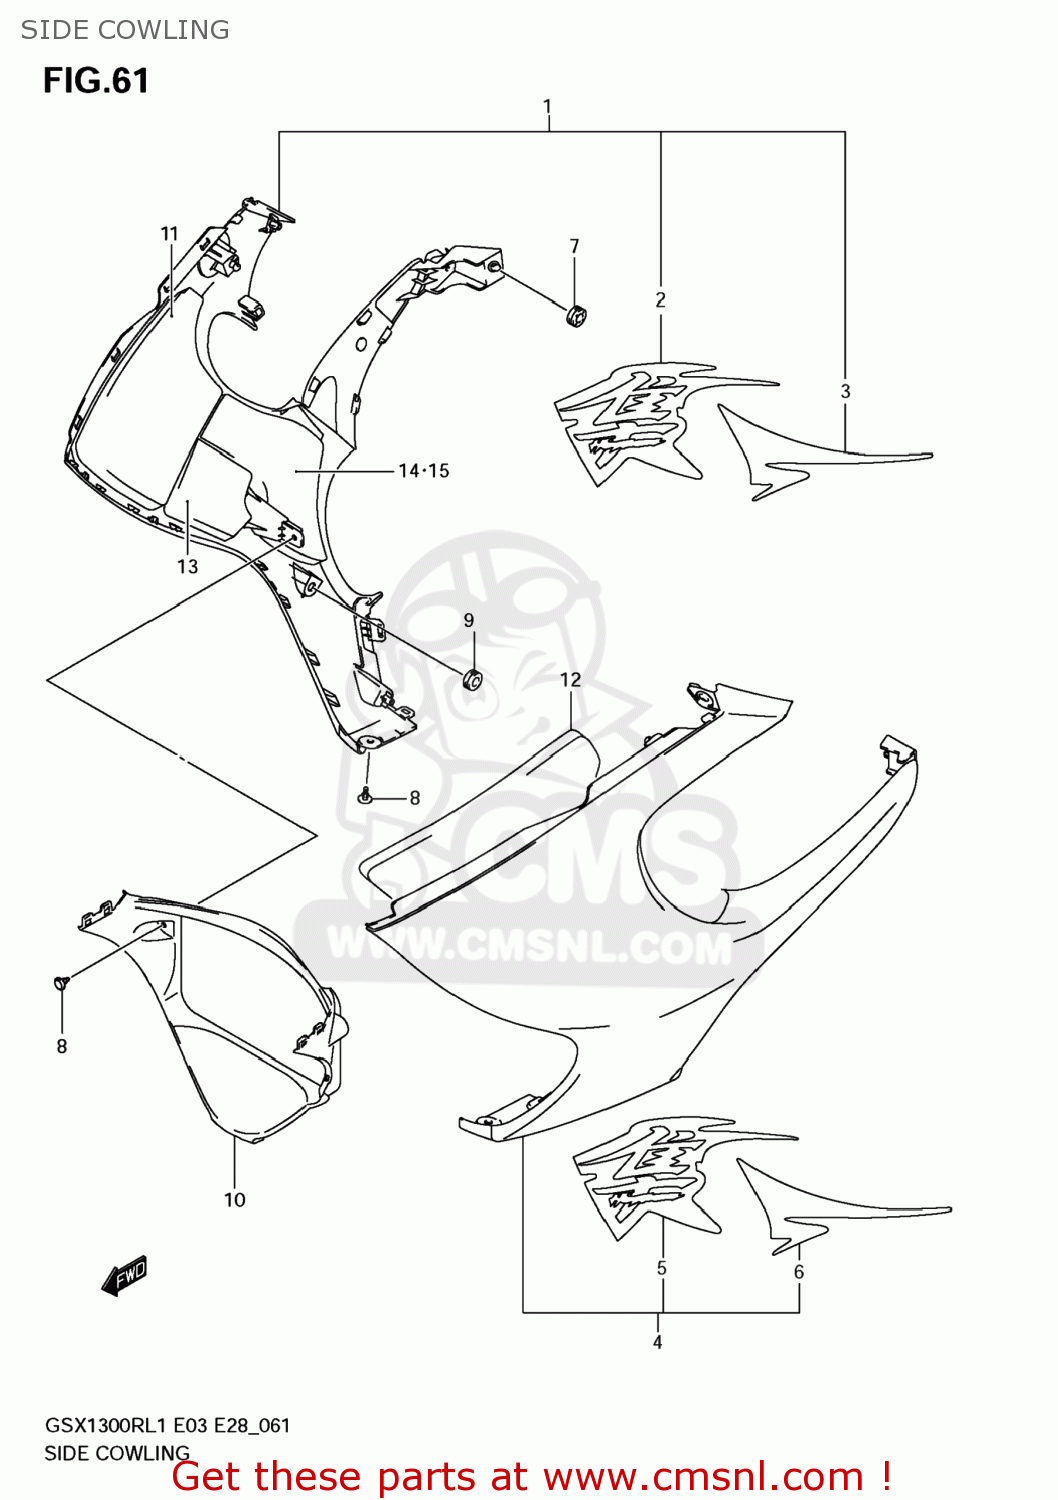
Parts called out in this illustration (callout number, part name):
1	COWLING,SIDE,R(BLUE)
2	TAPE,SIDE COWL UPR,R
3	TAPE,SIDE COWL LWR,R
4	COWLING,SIDE,L(BLUE)
5	TAPE,SIDE COWL UPR,L
6	TAPE,SIDE COWL LWR,L
7	CUSHION
8	CLIP
9	CUSHION
10	COWLING,UNDER CTR
11	CUSHION,SIDE COWL,R
12	CUSHION,SIDE COWL,L
13	CUSHION,SIDE COWL
14	SHIELD,SIDE COWL,R
15	SHIELD,SIDE COWL,L
